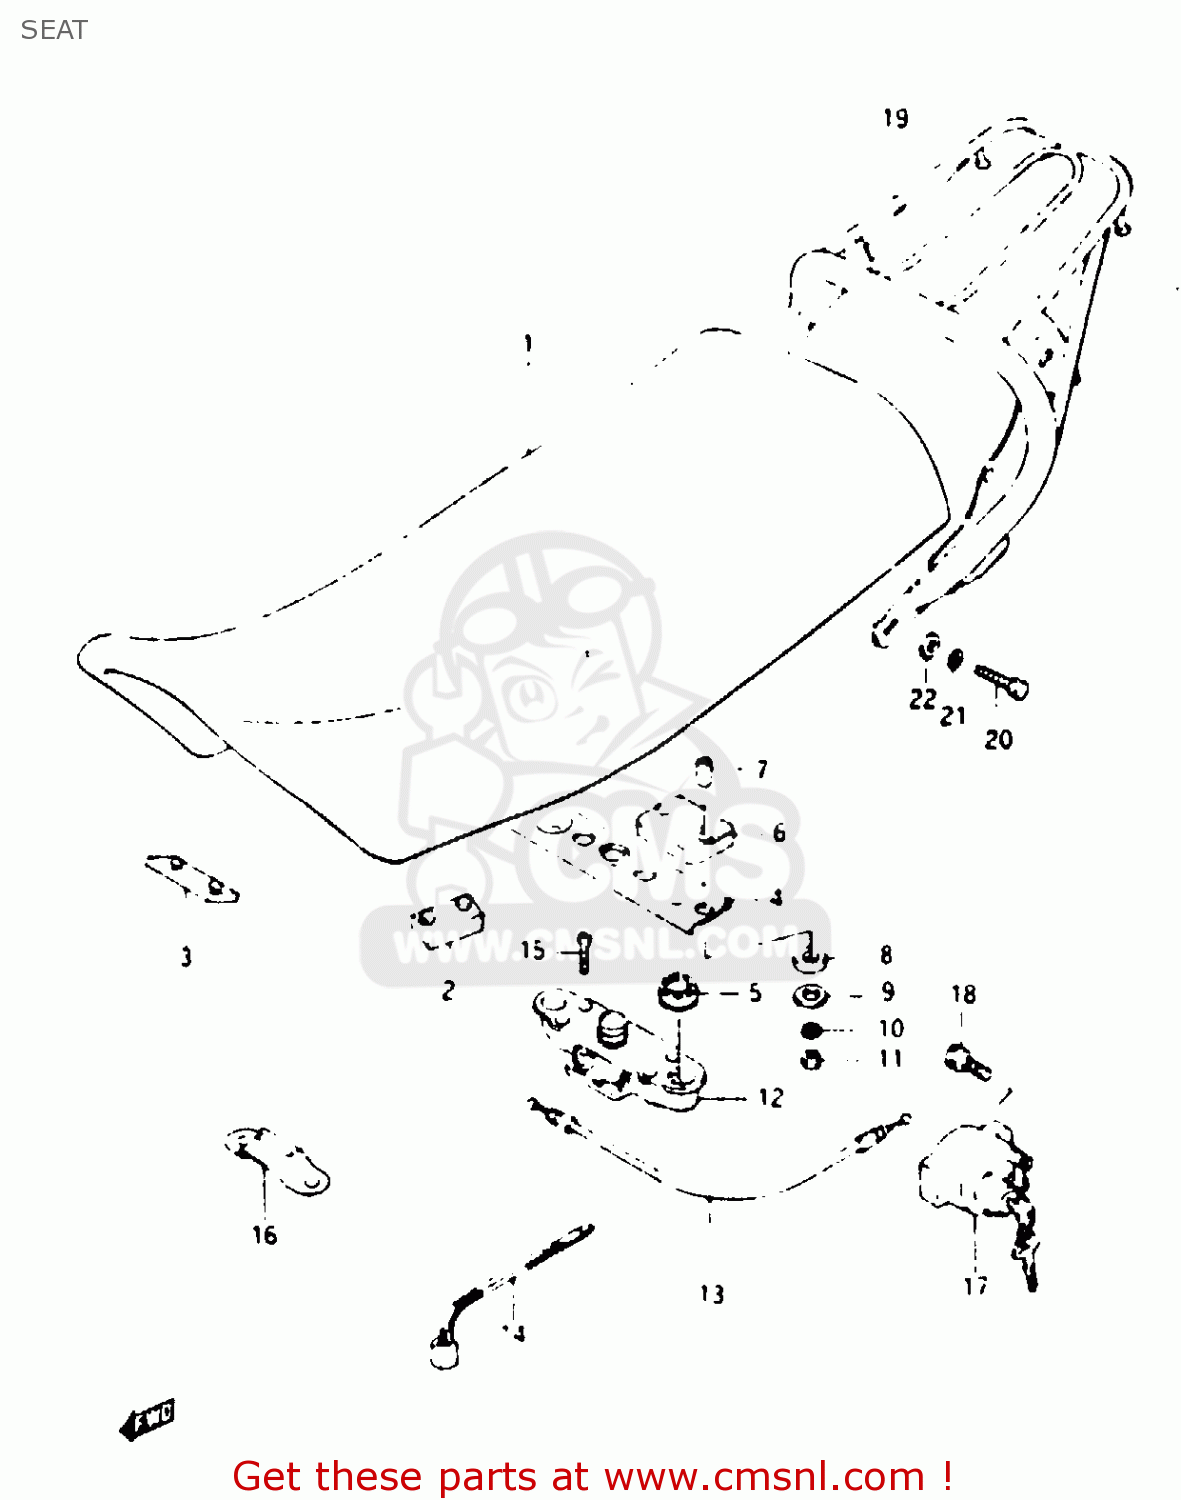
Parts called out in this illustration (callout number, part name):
1	SEAT SET
2	CUSHION
3	CUSHION
4	STRIKER, SEAT LOCK
5	CUSHION
6	CUSHION, SEAT LOCK UPPER
7	SPACER,SEAT SUPPORT
8	CUSHION,SEAT FR
9	WASHER
10	WASHER,LOCK
11	NUT 6MM
12	LOCK ASSY,SEAT STRIKER
13	CABLE,SEAT LOCK CABLE
14	CLAMP(L:165)
15	SCREW
16	PLATE,SEAT FR HOOK
17	LOCK ASSY, SEAT & HELMET
18	BOLT
19	CARRIER, SPORT
20	BOLT
21	WASHER,LOCK,8.
22	WASHER
